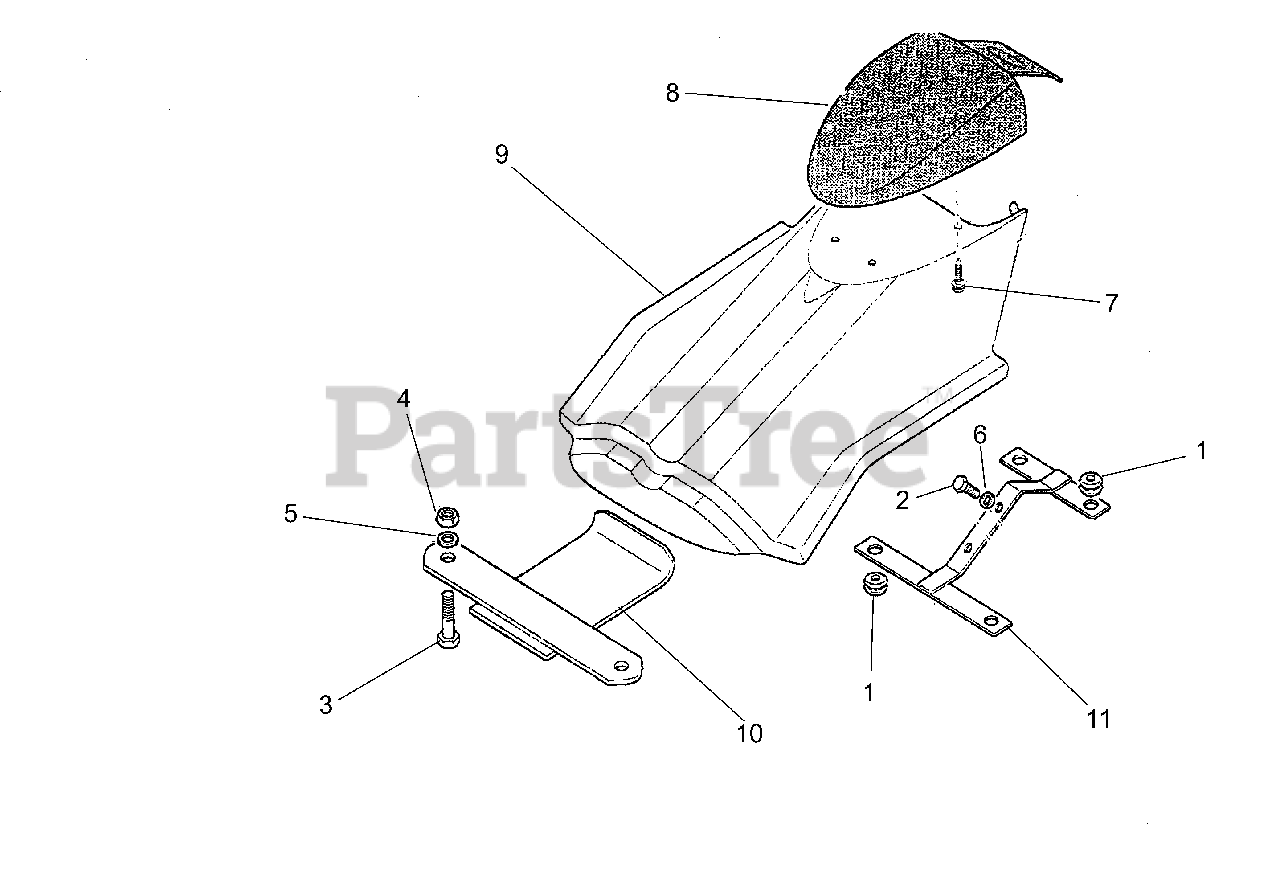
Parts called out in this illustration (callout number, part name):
2	HEX. SCREW M8X20 UNI 5739-8G
3	HEX SCREW M8X40
4	LOCKNUT M 8
5	WASHER P.8,4X17 UNI 6592
6	SUPER WASHER 8 DIN6796 GALV.
7	TAPPING SCREW HEX 6.3X19
8	TOP GUARD MF
9	BCS BODYGUARD
10	ENGINE PROTECTION
11	LOW BODYGUARD SUPPORT
